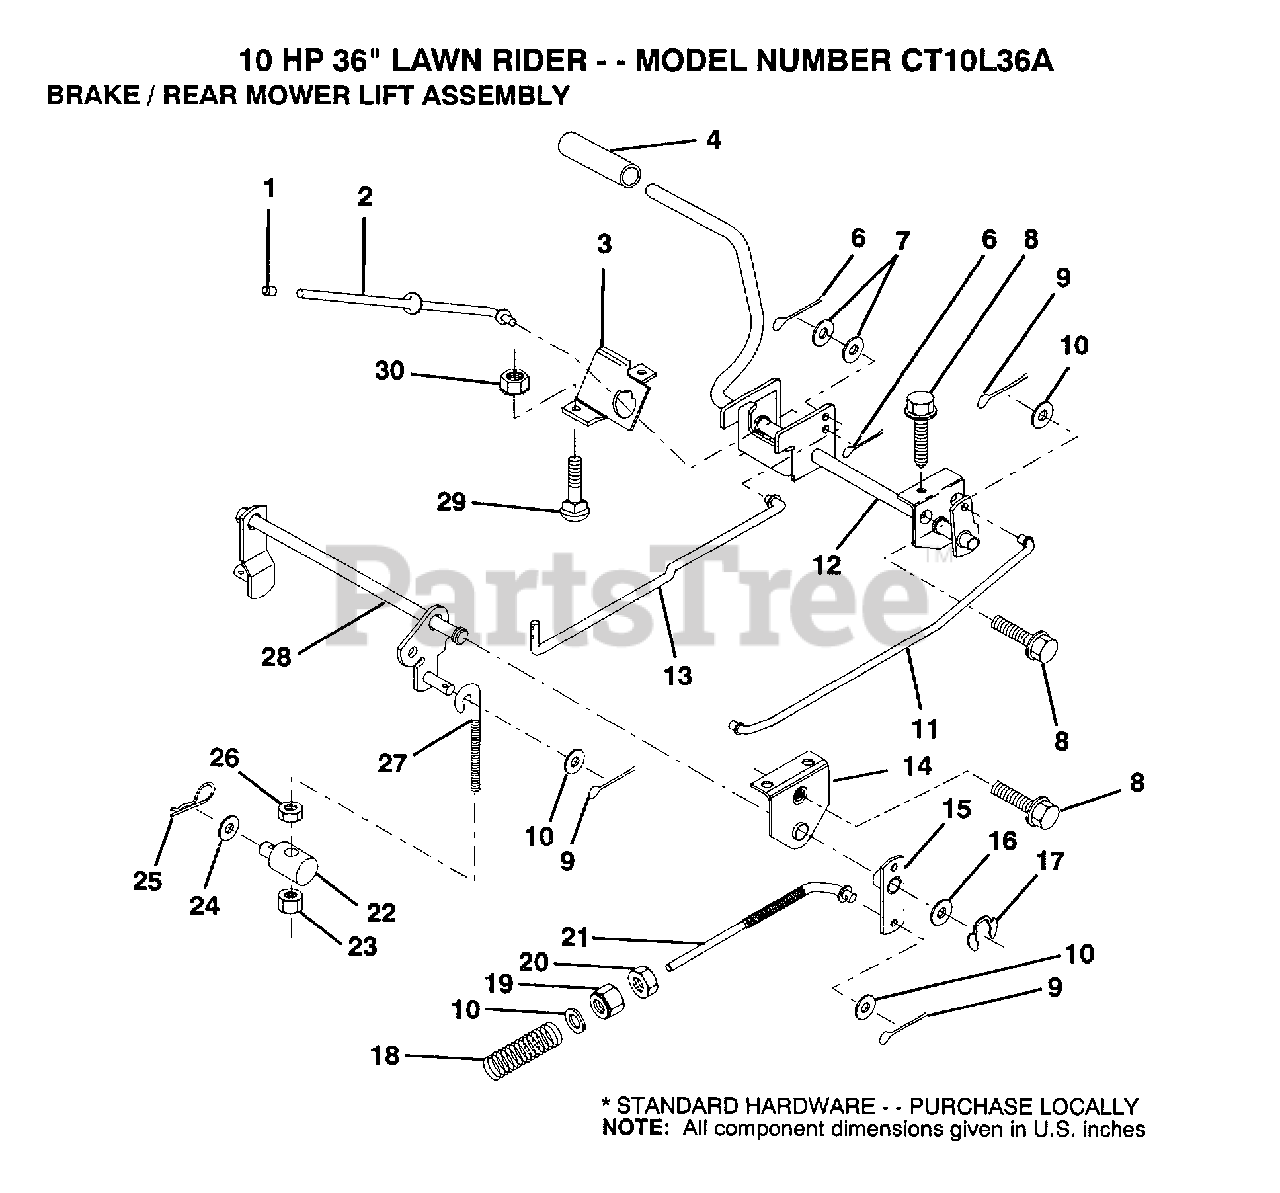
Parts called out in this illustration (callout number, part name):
1	PLUNGER CAP T
2	"ROD,PARK BRAKE"
3	"BRKT,PARK BRAKE"
4	FOOT PEDAL COVER
7	WASHER
8	SCREW LT
9	COTTER PIN
10	WASHER
13	"ROD,CLUTCH"
14	"BRKT,LIFT SHAFT"
15	PVT BRAKE ARM ASM
16	WASHER T
17	KLIP RING
18	SPRING ROD LT
20	NUT
24	WASHER
25	SPRING.RETAINER
26	LOCKNUT
27	"LINK, MOWER REAR"
